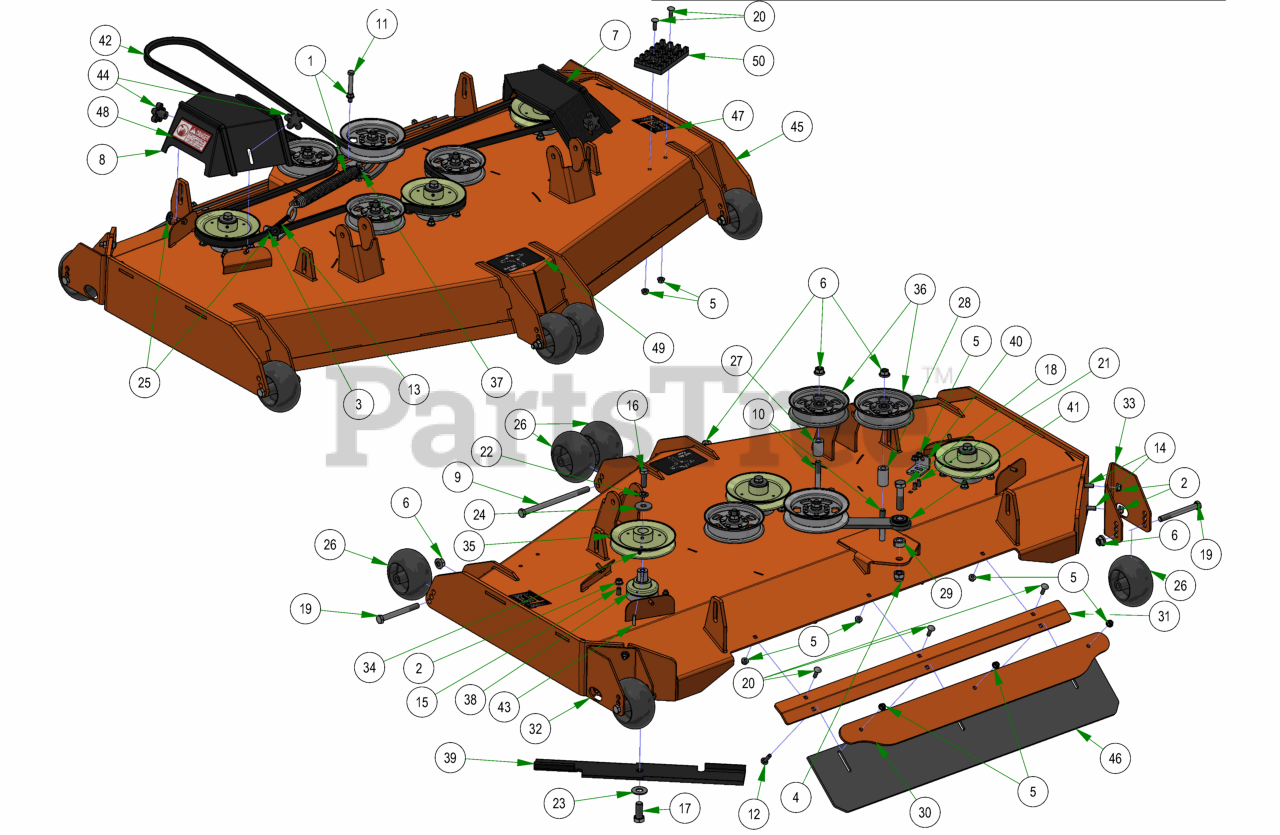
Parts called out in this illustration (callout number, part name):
1	3/8-16 HEX SERRATED FLANGE NUT HARD/ZINC
2	3/8-16 NYLON INSERT FLANGE LOCKNUT (GR.F) ZINC
3	3/8-16 HEX NUT ZINC
4	5/8-11 NYLON INSERT LOCKNUT ZINC
5	5/16-18 NYLON INSERT FLANGE LOCKNUT ZINC
6	1/2-13 NYLON INSERT FLANGE LOCKNUT ZINC
7	2019 61" Outlaw Gen2 Pulley Cover Left
8	2019 61" Outlaw Gen2 Pulley Cover Right
9	1/2-13 X 8 HEX CAP SCREW GR 5 ZINC
10	1/2-13 X 3-1/2 HEX FLANGE BOLT (GR.8) ZINC
11	3/8-16 X 3 HEX CAP SCREW (GR.5) ZINC
12	5/16-18 X 1-1/4 CARRIAGE BOLT ZINC
13	4" 3/8-16 Eye Bolt
14	3/8-16 X 1-1/4 CARRIAGE BOLT ZINC
15	3/8-16 X 1-1/2 HEX CAP SCREW (GR.5) ZINC
16	1/2-20 X 1-1/2 HEX CAP SCREW (GR.5) ZINC
17	5/8-18 X 1-1/2 HEX CAP SCREW (GR.8) ZINC YELLOW
18	5/8-11 X 2-1/2 HEX CAP SCREW (GR.5) ZINC
19	1/2-13 X 4-1/2 HEX CAP SCREW (GR.5) ZINC
20	5/16-18 X 1 CARRIAGE BOLT (GR.8) ZINC
21	5/16-18 X 7/8 CARRIAGE BOLT ZINC
22	1/2 SPLIT LOCKWASHER (GR.8) ZINC/YELLOW
23	5/8 USS FLAT WASHER (1-3/4" OD) GR.8 ZINC YELLOW
24	1/2 BELLEVILLE WASHER (1-5/8 OD X .140 THK) ZINC
25	.360 ID X .983 OD X .120 THICK FLAT WASHER NYLON BLACK
26	2019 Deck Wheel
27	.502 ID X .750 OD X 1.500 Long Spacer
28	1 3/4" Pulley Spacer
29	5/8 SOLID SHAFT COLLAR (W/1 SET SCREW) ZINC
30	61 Bolt in Baffle Deck v2 Stripping Plate
31	Rubber Mount Plate - Rear Discharge
32	LH Rear Deck Wheel Bracket - Rear Discharge
33	RH Rear Deck Wheel Bracket - Rear Discharge
34	5/16-24 X 1/4 SOCKET SET SCREW (CUP PT) PLAIN
35	6 1/4" Drive Pulley
36	5-3/4 Idler Pulley
37	2019 Outlaw Gen2 Deck Spring
38	OUTLAW SPINDLE ASSEMBLY
39	61 inch Fusion Blade
40	2019 Deck Eye Bolt Tab
41	2019 Rebel Rogue Deck Idler
43	1/4 X 1 SQ MACHINERY KEY 1018 STL PLN
44	5/16" Knob
45	61 Rear Discharge Deck
46	R Series Rubber For Deck
47	61" Deck Decal
48	Danger Decal-Spindle/Discharge
49	2019 Rebel & Rogue Deck Belt Route Decal
50	Deck Step Assembly
